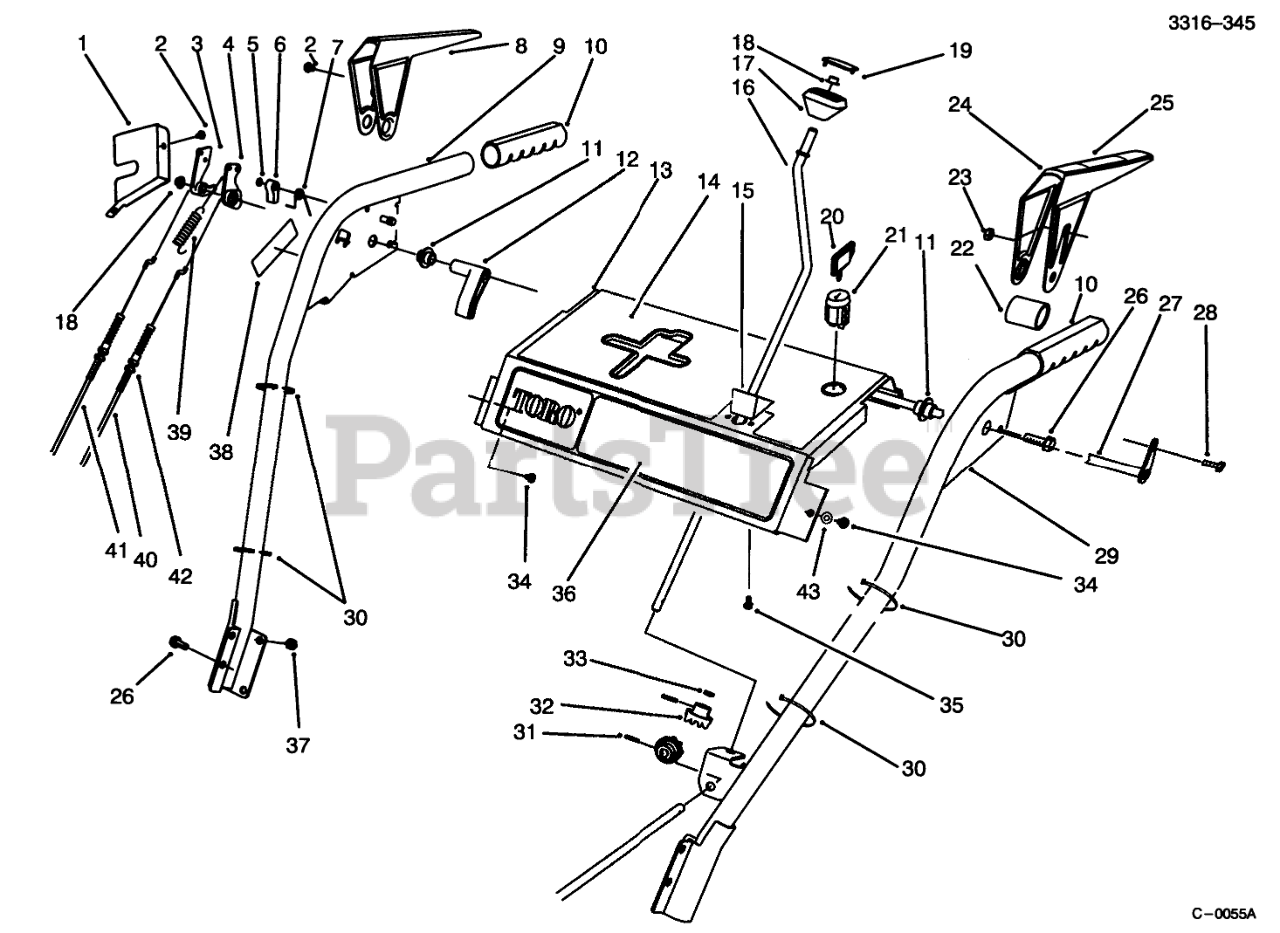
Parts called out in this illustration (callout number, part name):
1	Cover Lever Lock
2	SCREW-HH
3	TANG-LOCKING
4	CAM-RELEASE
5	E-RING-RETAINER
6	LATCH-LOCKING
7	SPRING-TORSION
8	Lever-Impeller
9	Handle-R.H.
10	GRIP-HANDLE
11	BUSHING-LEVER
12	LEVER-TRIP
13	Panel-Control
14	Decal-Panel, Top
15	PLATE-GUIDE
16	CRANK-ROD, CHUTE
17	KNOB-CONTROL, CHUTE
18	RETAINER-PUSH ON
19	COVER-KNOB
20	KEY-IGNITION
21	SWITCH
22	SPACER-LEVER, TRACTION
23	NUT-LOCK, NI
24	Lever-Traction
25	DECAL-LEVER
26	SCREW-HHF
27	CROSS ROD ASM
28	SCREW-HWH
29	Handle-L.H.
30	TIE-CABLE
31	PIN-SPRING
32	GEAR-UNIVERSAL
33	WASHER-RUBBER
34	SCREW-HWHTF
35	SCREW-PPH
36	DECAL - FRONT PANEL
37	NUT-LOCK, NI
38	DECAL-WARNING
39	SPRING-EXTENSION
40	CABLE-TRACTION
41	CABLE-IMPELLER
42	NUT-LOCK, NI
43	WASHER-FLAT
